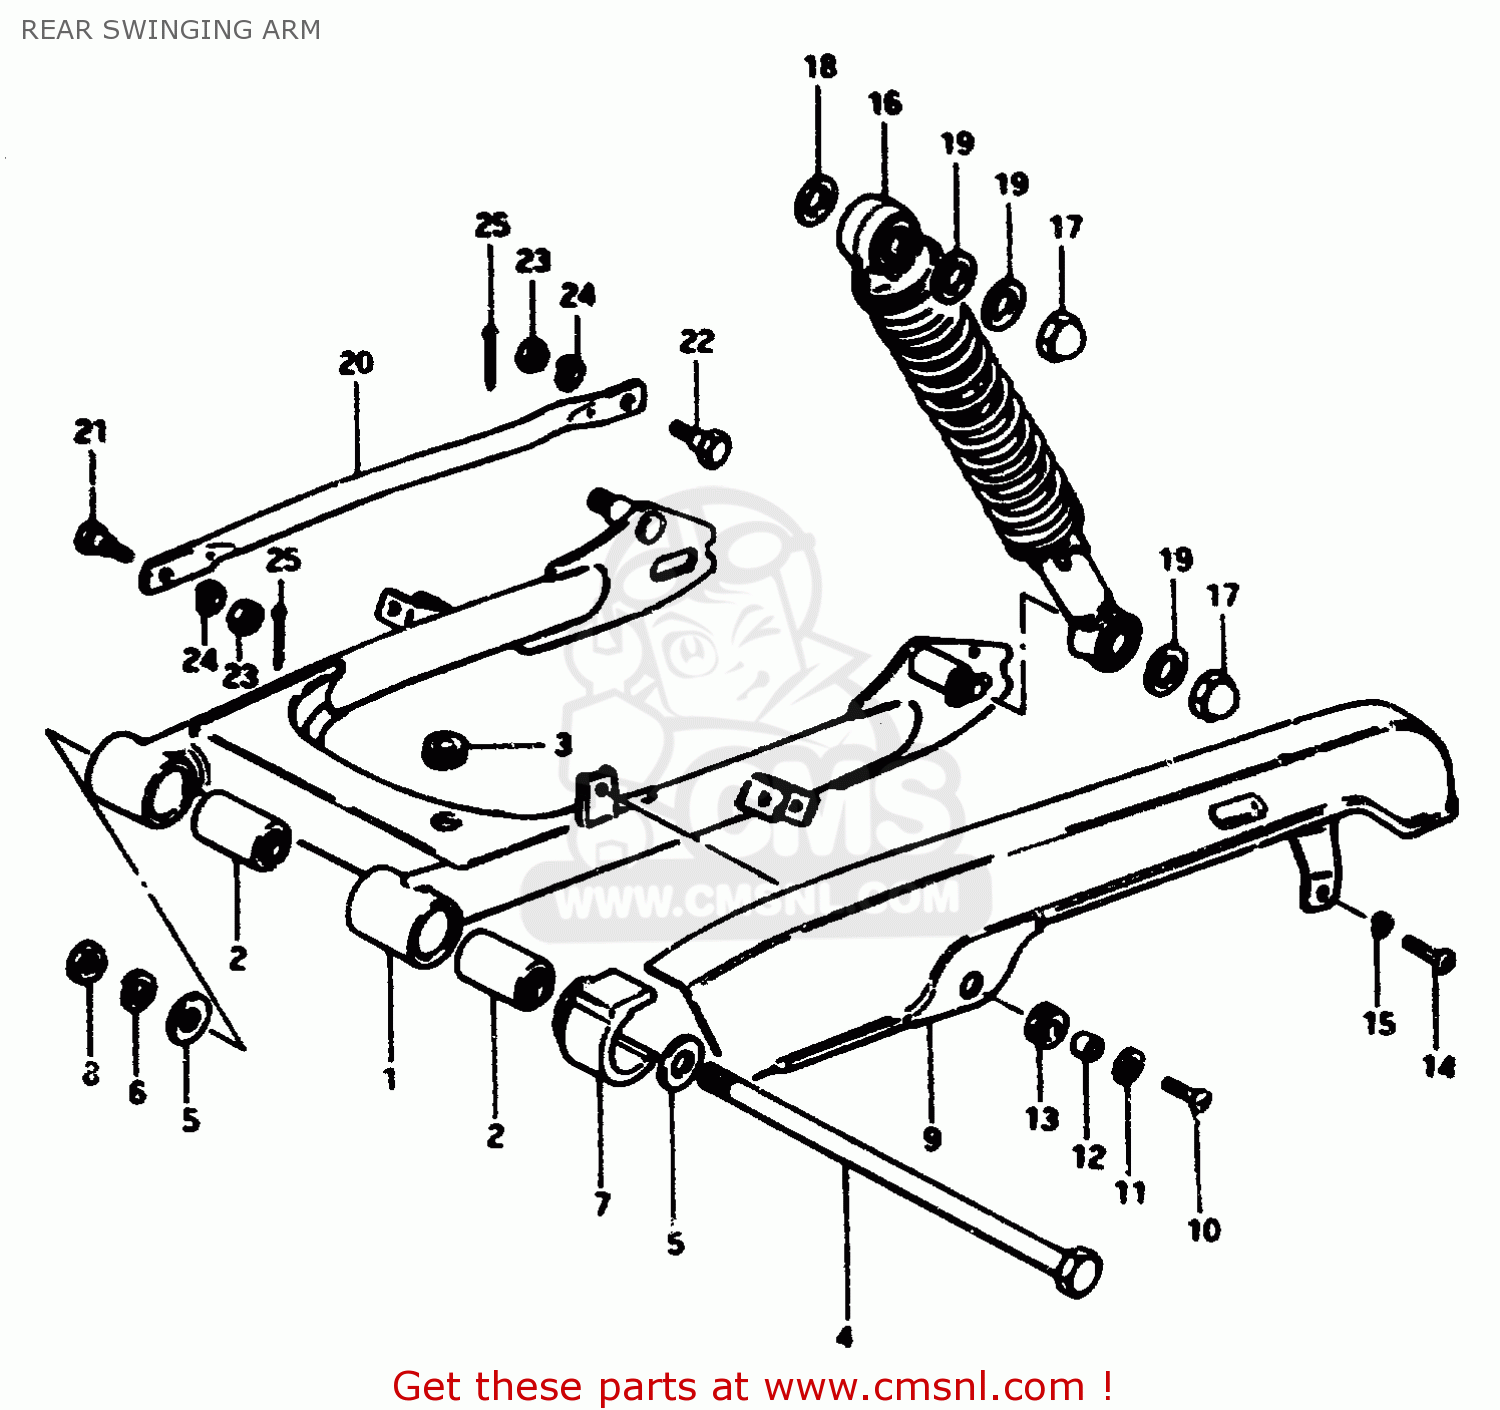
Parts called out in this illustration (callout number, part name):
1	SWINGING ARM SET, REAR
2	BUSH
3	CUSHION
4	SHAFT,RR SHOCK ABSORBER UPR
5	WASHER
6	LOCK WASHER
7	BUFFER,CHAIN TOUCH DEFENSE
8	NUT
9	CHAIN CASE
10	SCREW 6X12
11	WASHER (6.5X20X1.2)
12	SPACER (7X9X7)
13	CUSHION
14	SCREW 6X12
15	LOCK WASHER
16	SHOCK ABSORBER, REAR
17	NUT, LOWER LH
18	WASHER
19	WASHER
20	TORQUE LINK, REAR
21	BOLT(8X22)
22	BOLT(8X26.5)
23	NUT
24	LOCK WASHER
25	PIN 20X20
